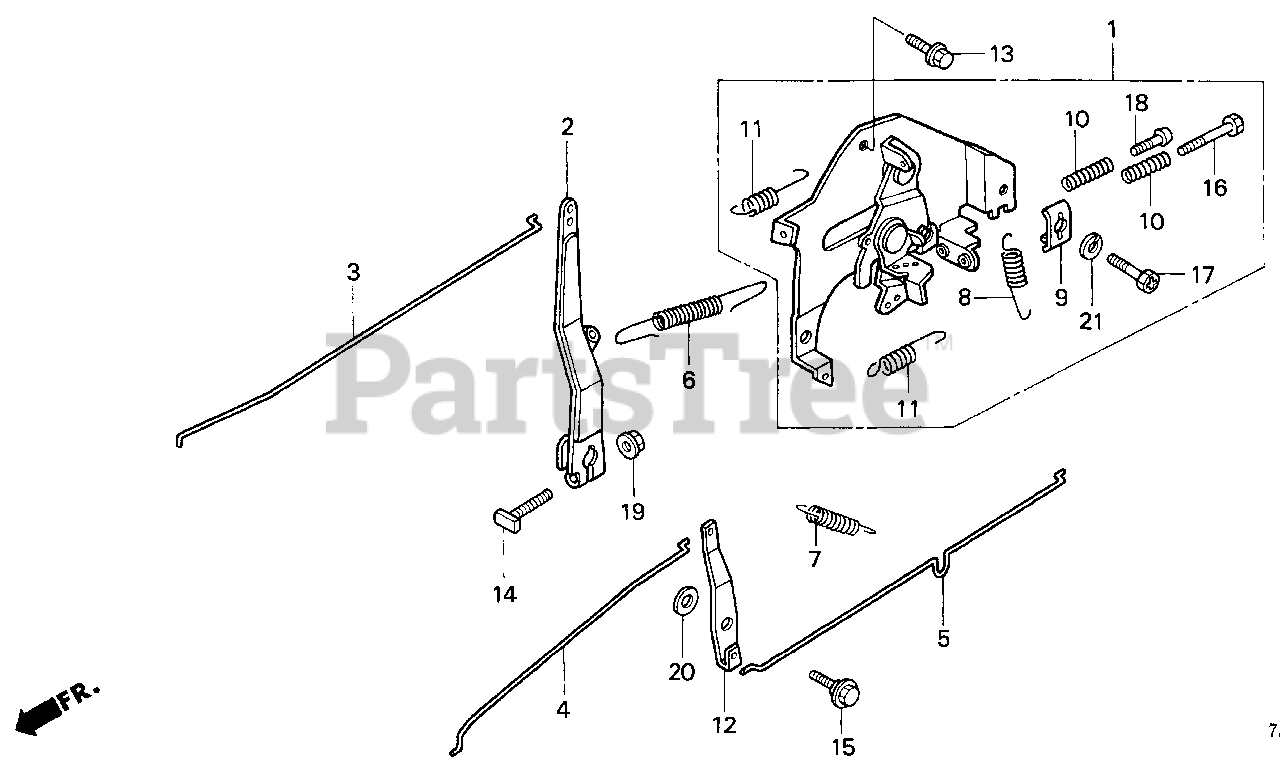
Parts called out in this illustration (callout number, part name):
1	CONTROL ASSY.
2	ARM, GOVERNOR
3	ROD, GOVERNOR
4	ROD, CHOKE
5	ROD, JOINT
6	SPRING, GOVERNOR
7	SPRING, GOVERNOR PRIMARY
8	SPRING, LEVER
9	HOLDER, CABLE
10	SPRING, CONTROL ADJUSTING
11	SPRING, CABLE RETURN
12	LEVER, CHOKE JOINT
13	BOLT, FLANGE (6X12) (CT200)
14	BOLT, GOVERNOR ARM
15	BOLT, FLANGE (6MM)
16	BOLT, RECESSED (5X34)
17	BOLT, RECESSED (5X16)
18	SCREW, PAN (5X20)
19	NUT, FLANGE (6MM)
20	WASHER, PLAIN (6MM)
21	WASHER, SPRING (5MM)
